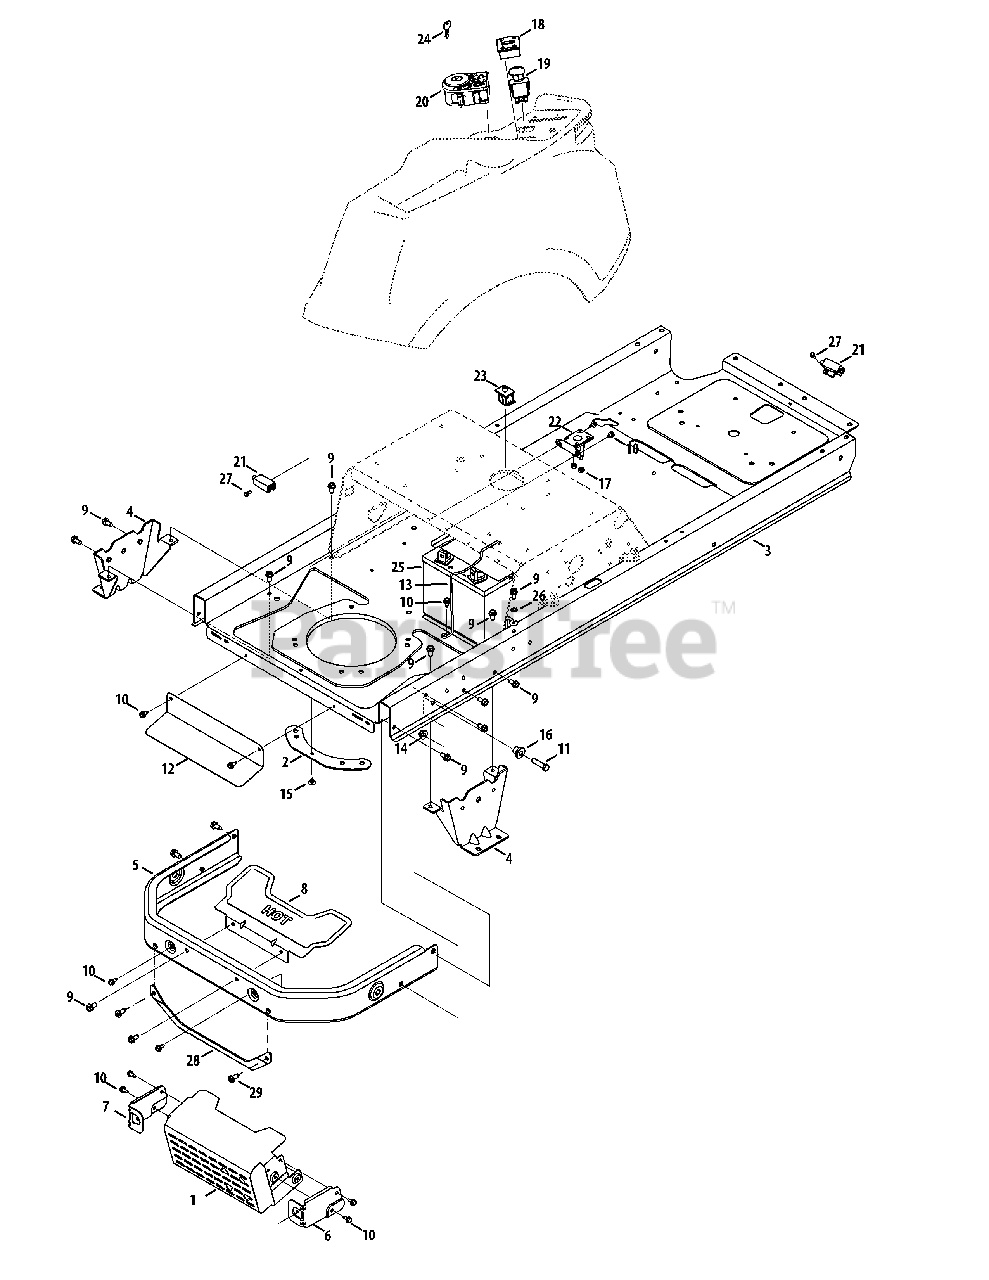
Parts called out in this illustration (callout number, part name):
1	Muffler Shield Assembly
2	Retainer Plate
3	Frame Assembly
4	Transmission Mounting Bracket
5	Rear Bumper
6	Muffler Mounting Shield Bracket, RH
7	Muffler Mounting Shield Bracket, LH
8	Muffler Shield
9	Hex Washer Screw 5/16-18 x .750
10	Hex Washer Screw 1/4-20 x .625
11	Hex Screw 3/8-16 x 1.25
12	Lower Heat Shield
13	Battery Rod
14	Flange Lock Nut, 3/8-16
15	Clip .250 Dia. x .500 LG
16	Shoulder Spacer .38 x 1.0 x .70
17	Flange Lock Nut 1/4-20
18	Hour Meter/Service Minder
19	Electric PTO Switch
20	Key Switch
21	Interlock Switch
22	Solenoid
23	Seat Switch
24	Key, Assembly
25	Battery
26	Lock Washer 5/16
27	Shoulder Screw #10-32 x .500
28	Muffler Shield Bracket
29	TT Screw 5/16-18 x .75
